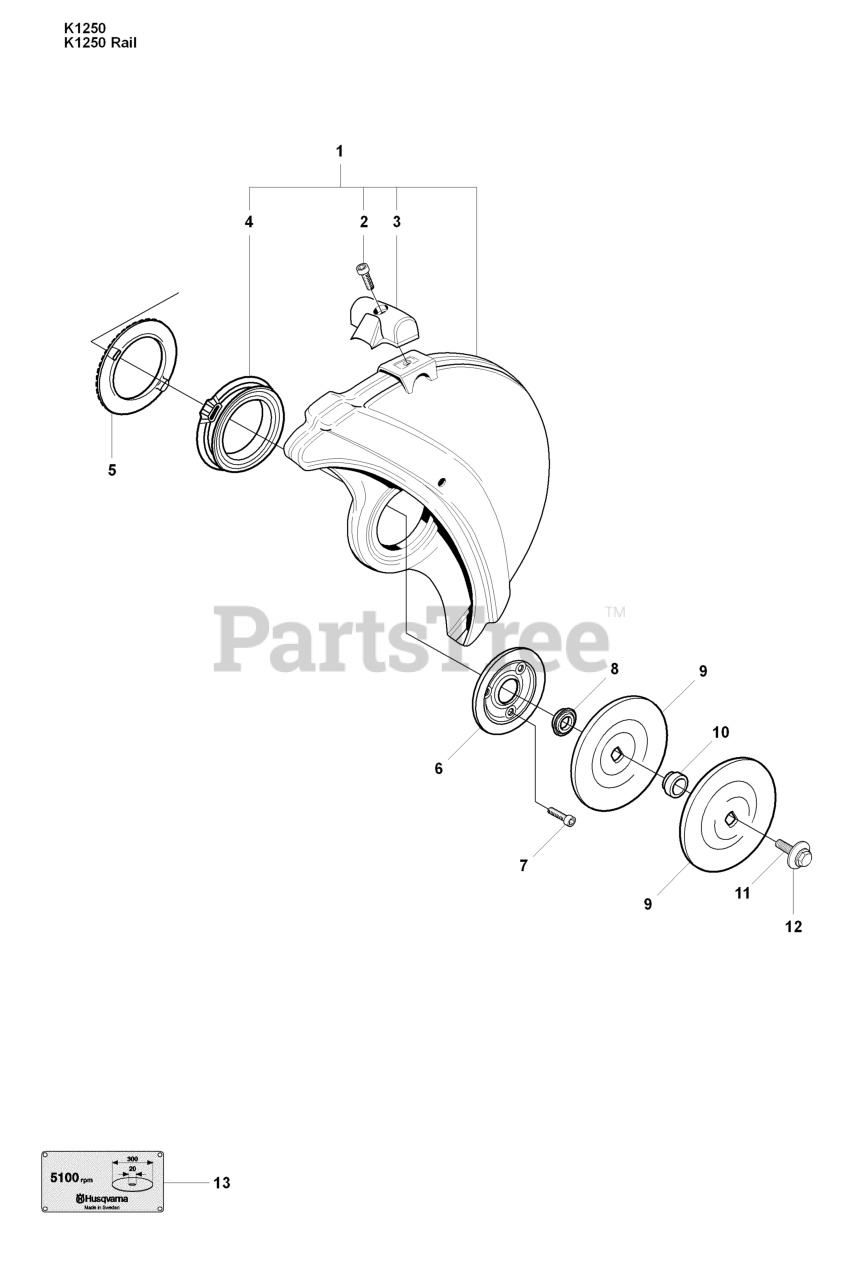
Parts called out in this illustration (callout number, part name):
1	PROTECTOR
1	RP GUARD
2	SCREW MC6S 5X20
7	SCREW MC6S 5X16
8	SLEEVE
9	WASHER
10	BUSHING
10	BUSHING-30MM
11	WASHER
12	SCREW
13	ARBOR SIZE DECAL/20
13	LABEL
13	ARBOR SIZE DECAL/25.4
